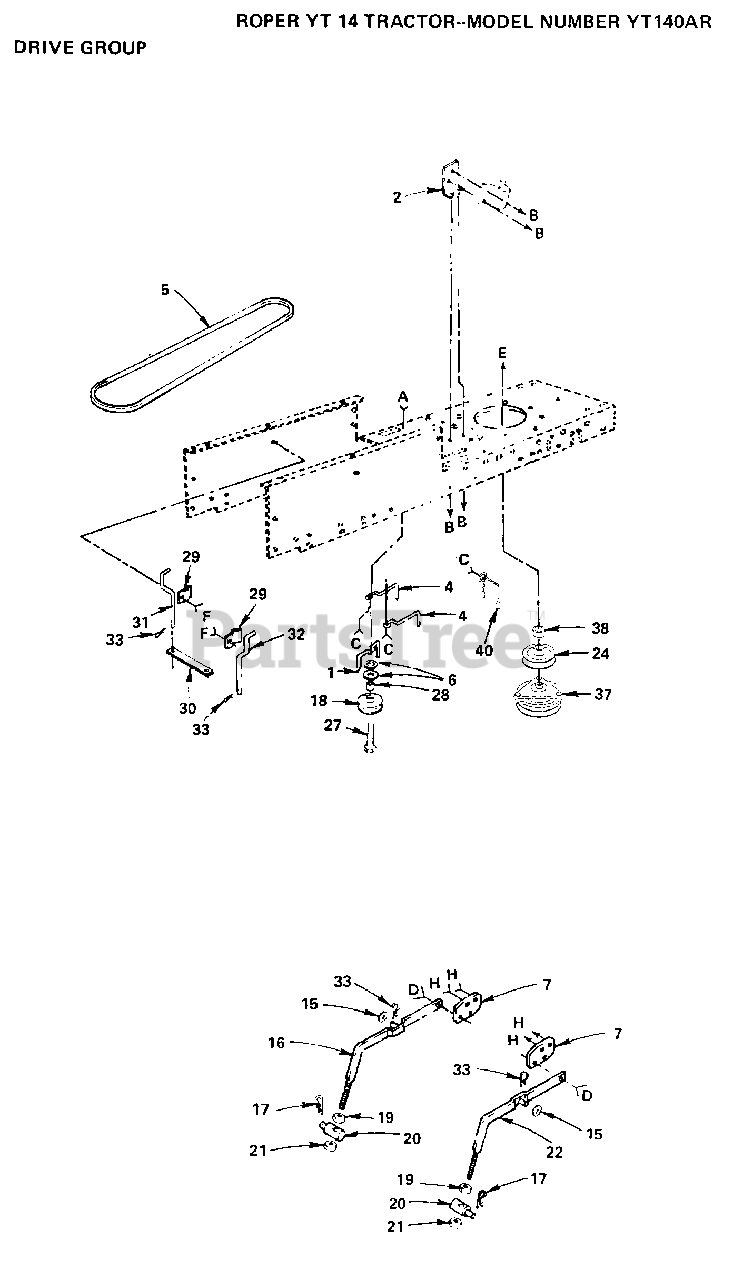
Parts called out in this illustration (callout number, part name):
2	BRACKET LT
4	"KEEPER,BLT ENG LT"
6	WASHER
7	"BRACKET, SUSPE T"
17	SPRING H
19	NUT
21	NUT LTV
24	PULLEY ENGINE T
27	BOLT
28	SPACER T
29	CLAMP LT
32	KEEPER BELT RH
33	SPRING.RETAINER
